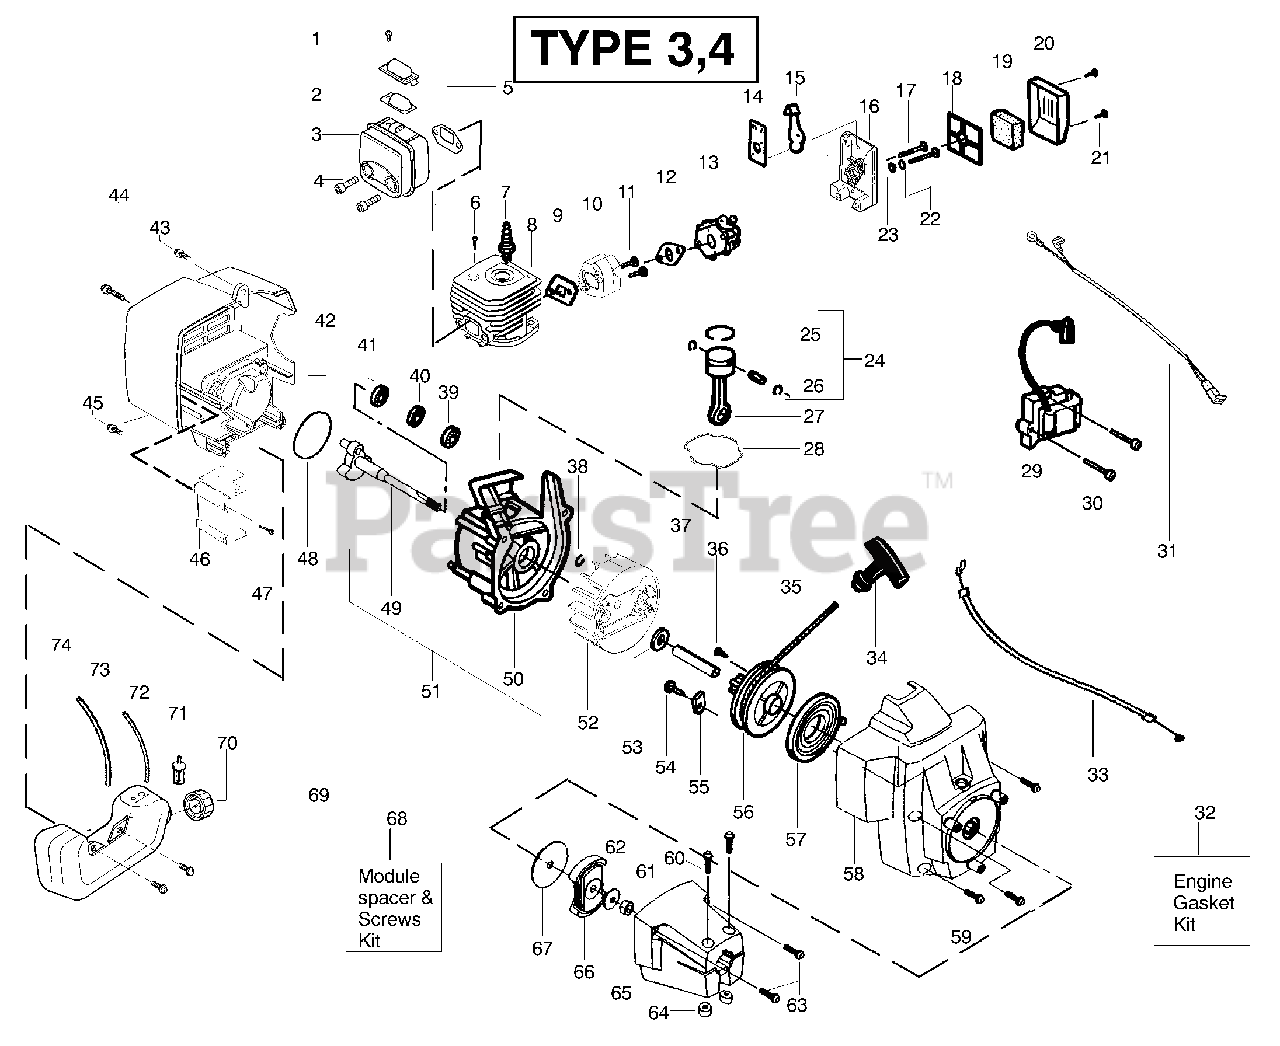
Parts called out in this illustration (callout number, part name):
1	Screw--Screen
2	Kit--Spark Arrestor
3	Kit -- Muffler
4	Bolt--Muffler
5	Gasket--Muffler(kit)
6	Screw--Cylinder
7	Spark Plug (RCJ 6Y)
8	Kit -- Cylinder
9	Gasket--Cyl/Carb(kit)
10	Adapter--Carb.
12	Gasket--Carb.(kit)
13	Kit--Carburetor (C1U--W16)
14	Choke Plate Mounting
15	Shutter--Choke
18	Plate -- Filter Support
19	Foam--Air Filter
20	Cover--Air Filter
22	Spacer--Choke
24	Kit -- Piston
25	Piston Ring
26	Retainer - Piston Pin
27	Assy--Connecting Rod
28	Seal--Cylinder (kit)
29	Ignition Module
31	Assy--Switch Wire
32	Kit--Engine Gasket
33	Assy--Throttle Cable
34	Handle--Starter
35	Kit -- Rope
37	Spacer--Flywheel
38	Retain. Ring--C'shaft
39	Outer Bearing
40	Kit--C'case Seal
41	Inner Bearing
42	Shroud--Rear
44	Screw
46	Shield--Heat
47	Screw
48	O--Ring--C'case(kit)
49	Assy--Crankshaft
50	Assy--Crankcase
51	Assy--C'case & C'shaft
52	Assy--Flywheel
55	Retainer
56	Kit--Starter Pull
57	Spring--Starter
58	Assy.--Fan Hsg
59	Screw
61	Assy--Clutch Hsg.
62	Washer--Flat
65	Nut--Clutch
66	Assy--Clutch
67	Washer--Clutch
68	Kit--Module Spacer & Screws
69	Retainer
70	Assy--Fuel Cap
71	Assy--Fuel Pickup
72	Kit--Fuel Line (Small)
73	Kit--Fuel Line (Large)
74	Assy--Fuel Tank
